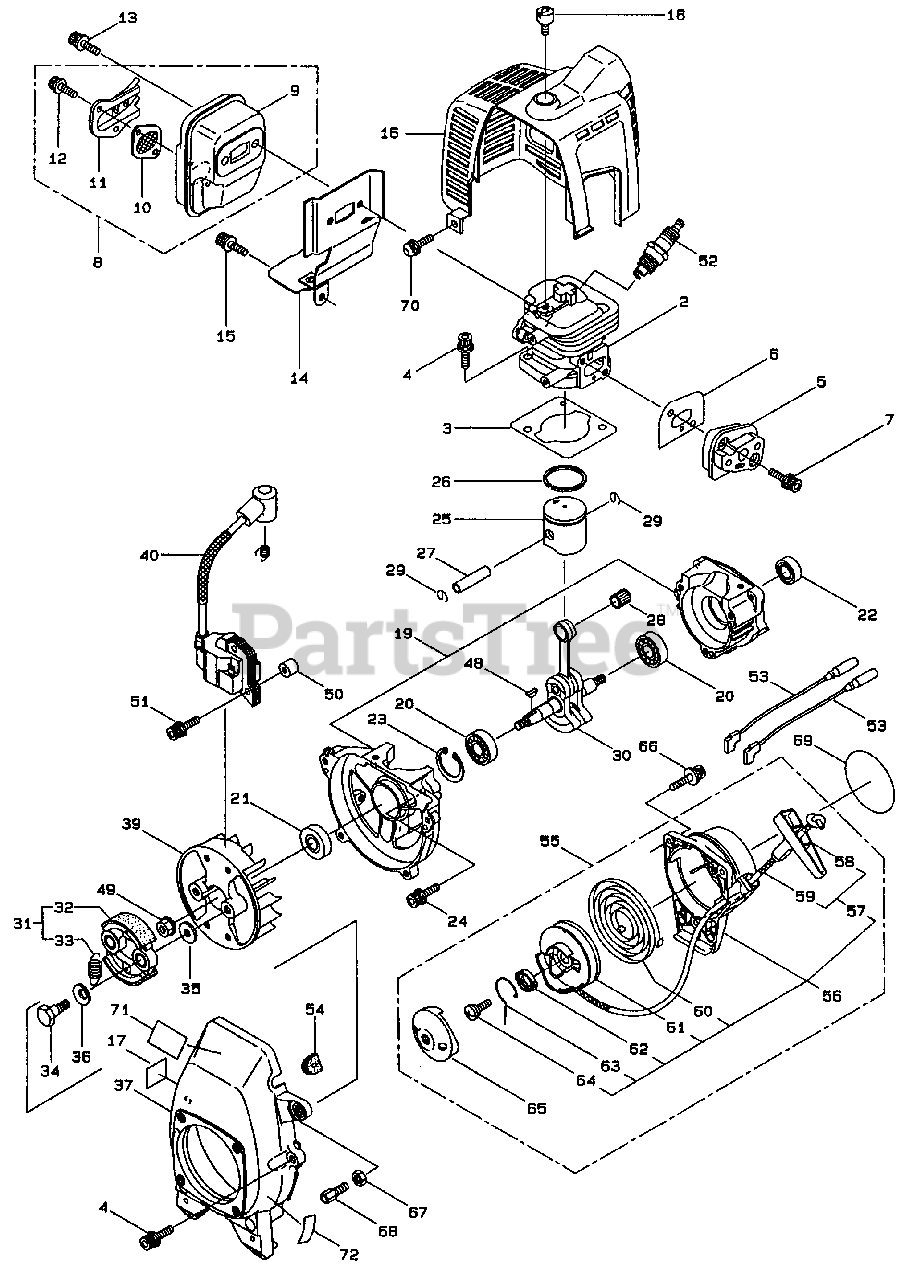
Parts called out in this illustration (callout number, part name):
2	Cylinder
4	Cap Screw
5	Insulator
7	Cap Screw
8	Muffler Asm (Incl. Ref. # 9-12)
9	Muffler Comp.
10	Spark Arrester
12	Cap Screw
13	Cap Screw
14	Gasket Comp.
15	Cap Screw
16	Top Cover Asm
17	Decal-Caution
19	Crankcase
21	Seal-Oil
22	Seal-Oil
23	Snap Ring
24	Cap Screw
26	Ring-Piston
27	Pin-Piston
28	Bearing-Needle
29	Clip-Piston
30	Crankshaft/Connecting Rod Asm
31	Clutch Asm (Incl. Ref. #32,33)
32	Shoe-Clutch
33	Spring-Clutch
36	Washer-Wave
37	Cover-Fan (Incl. Ref.#17)
39	Rotor-Fan
40	Ignition Coil Asm
48	Key-Woodruff
49	Nut-Rotor
51	Cap Screw
52	Spark Plug
53	Wire-Coil Ground
55	Recoil Starter Asm (Incl. Ref. #56-65)
56	Recoil Asm. (Incl. Ref. #57-64)
57	Rope Asm (Incl. Ref. #58,59)
58	Grip-Starter
59	Rope-Starter
60	Spring-Spiral
63	Arm-Swing
65	Pulley-Starter
66	Cap Screw
69	Decal-Toro (Round)
71	Decal-Toro
